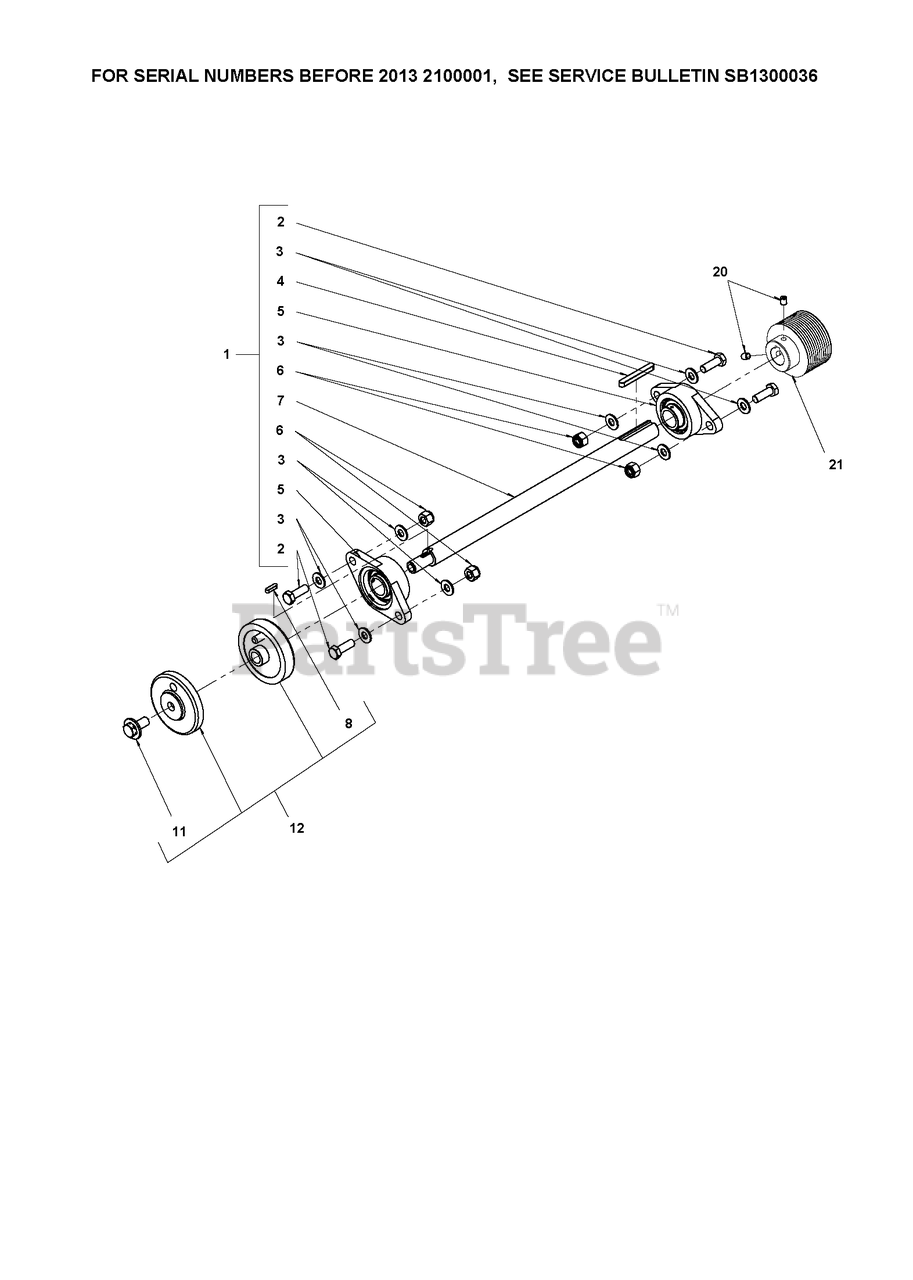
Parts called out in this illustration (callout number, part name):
1	BLADE SHAFTS/N before 2013 2100001, see service bulletin SB1300036
3	WASHER
6	HEXAGON LOCKING NUT
7	BLADE SHAFTS/N before 2013 2100001, see service bulletin SB1300036
8	KEYS/N before 2013 2100001, see service bulletin SB1300036
12	FLANGES/N before 2013 2100001, see service bulletin SB1300036
